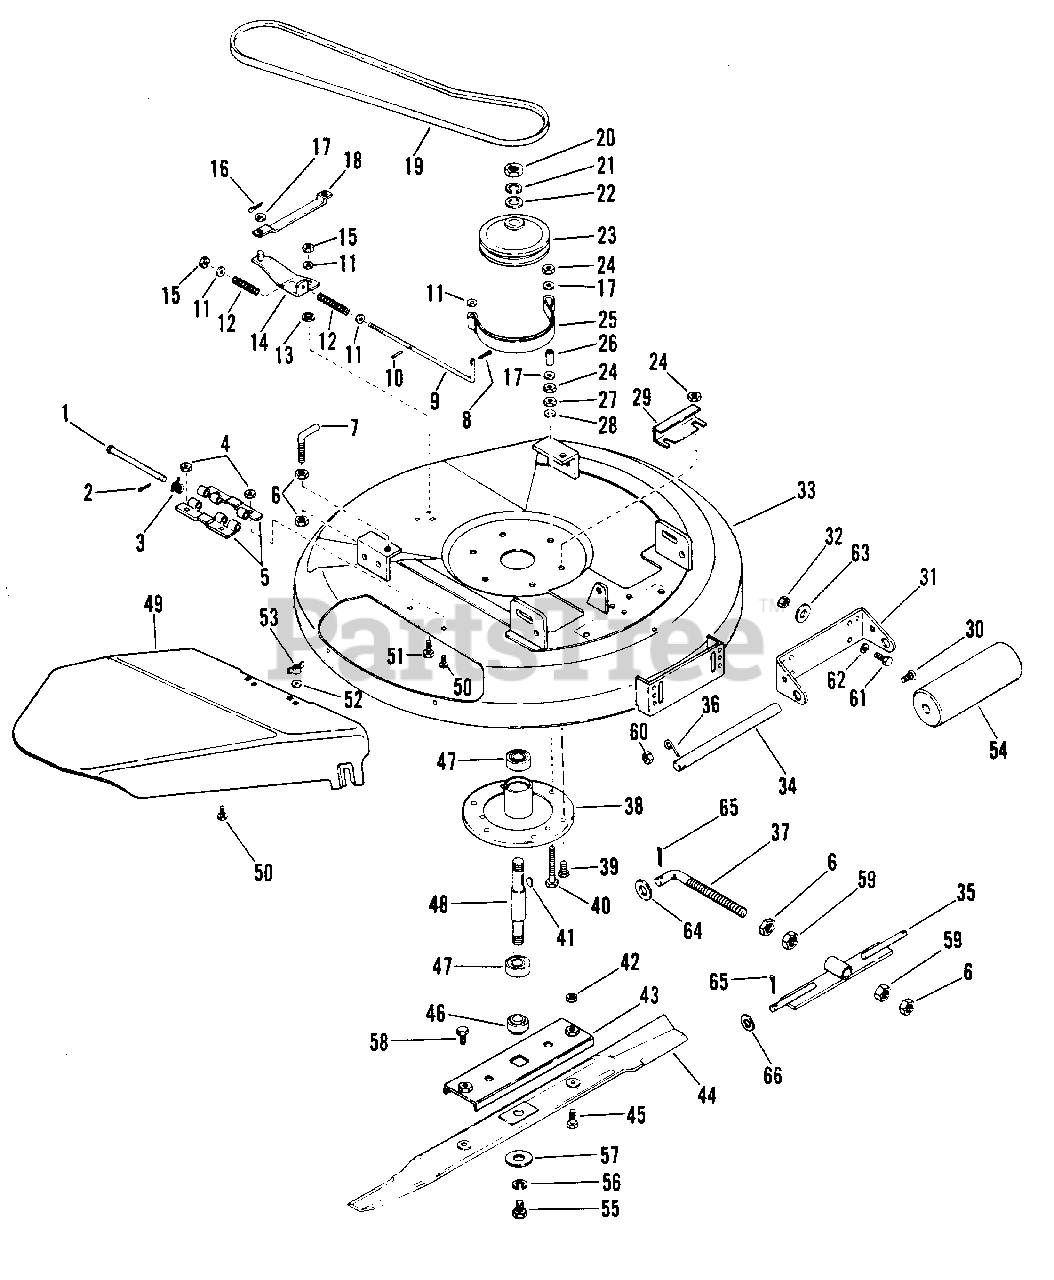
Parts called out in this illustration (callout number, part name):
1	PIN, HINGE
2	PIN, COTTER .09X.75
3	SPRING, TORSION .37 I.D.
4	NUT, LOCK 1/4-20
5	PLATE, HINGE
6	NUT, JAM 1/2-13 HEX
7	HOOK, HANGER
8	PIN, COTTER .09X.50
9	ROD, BRAKE
10	PIN, SPRING .125X1.000
11	WASHER, FLAT .312X.734X.065
12	SPRING
13	SPACER
14	ACTUATOR, BRAKE
15	NUT, LOCK 5/16-18
16	PIN, COTTER .125X1.00
17	WASHER, FLAT .406X.812X.065
18	STRAP
19	V-BELT
20	NUT, JAM 3/4-10 HEX
21	WASHER, LOCK 3/4 SP.
22	WASHER, FLAT .812X1.496X.134
23	SHEAVE, MOWER
24	NUT, LOCK 3/8-16
25	BAND, BRAKE
26	SPACER
27	NUT, HEX 3/8-16
28	WASHER, LOCK 3/8 REG.
29	SUPPORT, BRAKE BAND
30	BOLT, 1/4-20X.75 RD HD SQ NK
31	BRACKET, ROLLER
32	NUT, HEX 5/16-18
33	DECK, 32" MOWER
34	SHAFT, ROLLER
35	PLATE, ADJUSTMENT
36	PIN
37	LINK, ADJUSTMENT
38	HOUSING, SPINDLE
39	BOLT, HEX 3/8-16X.75
40	BOLT, HEX 3/8-16X3.00
41	KEY, WOODRUFF .187X.75 #9
42	NUT, LOCK 3/8-16
43	TRAY, BLADE
44	BLADE, 32" MOWER
45	BOLT, HEX 3/8-16X1.00
46	HUB, RETAINER
47	BEARING, RADIAL
48	SHAFT, SPINDLE
49	CHUTE, DEFLECTOR
50	BOLT, 1/4-20X.625 RD HD SQ NK
51	BOLT, HEX 5/16-18X.75
52	WASHER, FLAT .313X.875X.065
53	NUT, WING 5/16-18 TYPE B
54	ROLLER
55	BOLT, 7/16-20X1.75
56	WASHER, LOCK 7/16 SP. HEAVY
57	WASHER, FLAT .516/.484X1.141X.25
58	BOLT, 3/8-24X.75
59	NUT, HEX 1/2-13
60	NUT, LOCK 1/4-20
61	BOLT, HEX 5/16-18X1.00
62	WASHER, LOCK 5/16 REG.
63	WASHER, FLAT .375X.734X.065
64	WASHER, FLAT .531X1.062X.095
65	PIN, COTTER .125X1.00
66	WASHER, FLAT .500X1.250X.083
NS	DECAL, DANGER FOOT
NS	DECAL, NO STEP
NS	DECAL, CAUTION
NS	DECAL, WARNING EYE
NS	DECAL, DANGER HAND
